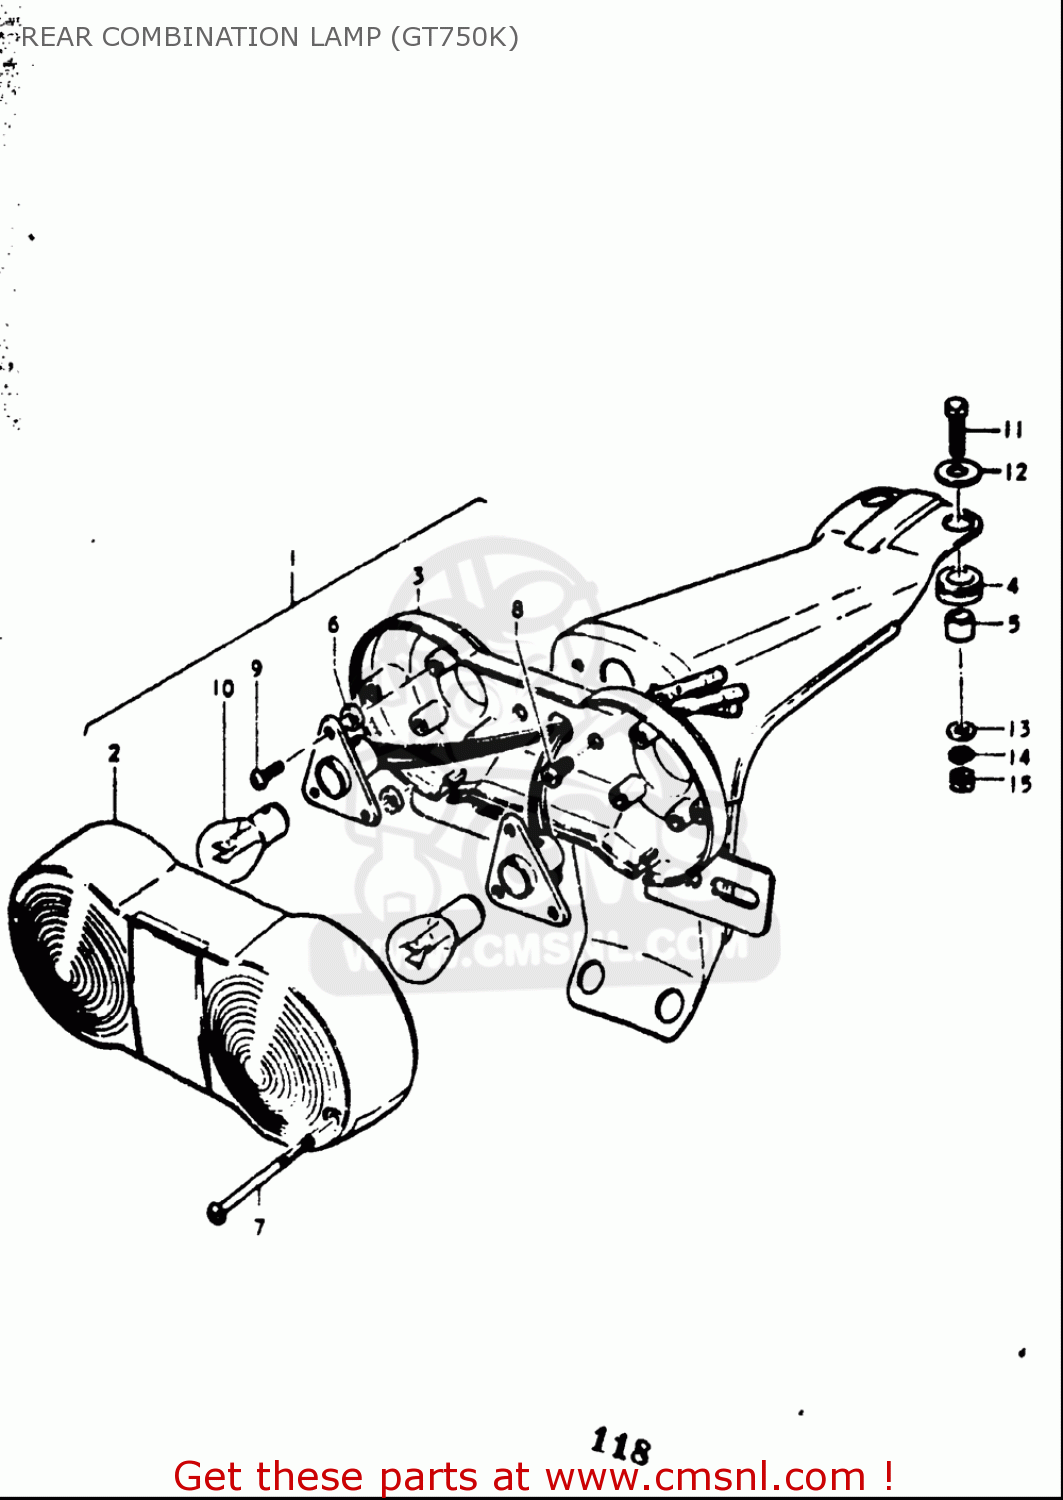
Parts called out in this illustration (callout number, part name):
2	LENS,REAR COMBINATION LAMP
4	CUSHION
5	SPACER
7	SCREW
8	SCREW
9	SCREW
10	BULB(12V23W)
11	BOLT 6X23
12	WASHER(6.5X20X1.6)
13	WASHER
14	WASHER,LOCK
15	NUT
